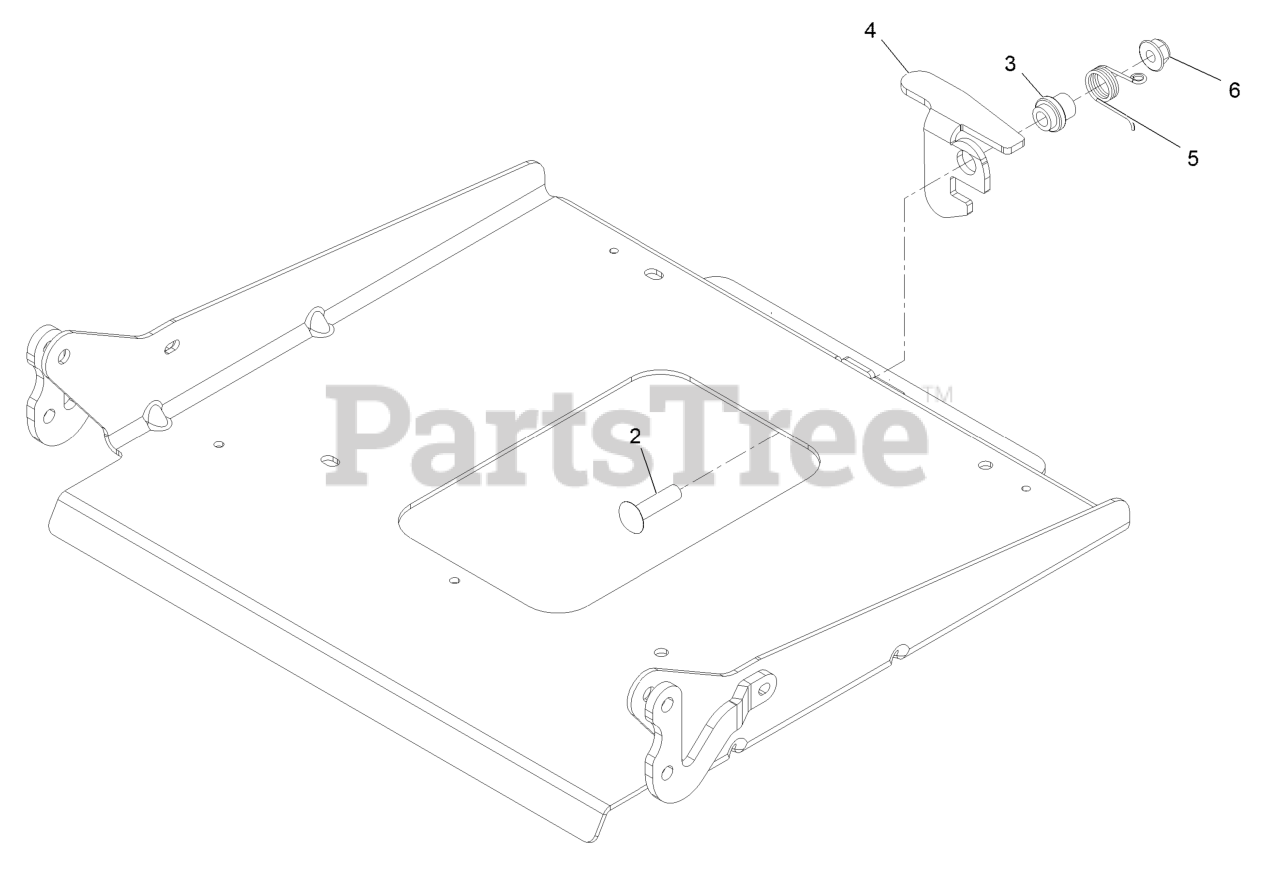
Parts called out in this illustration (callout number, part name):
2	SCREW-CARR
3	BUSHING-LATCH, SEAT
4	LATCH-CATCH, SINGLE
5	SPRING-TORSION, LATCH
6	NUT-HF, NI
